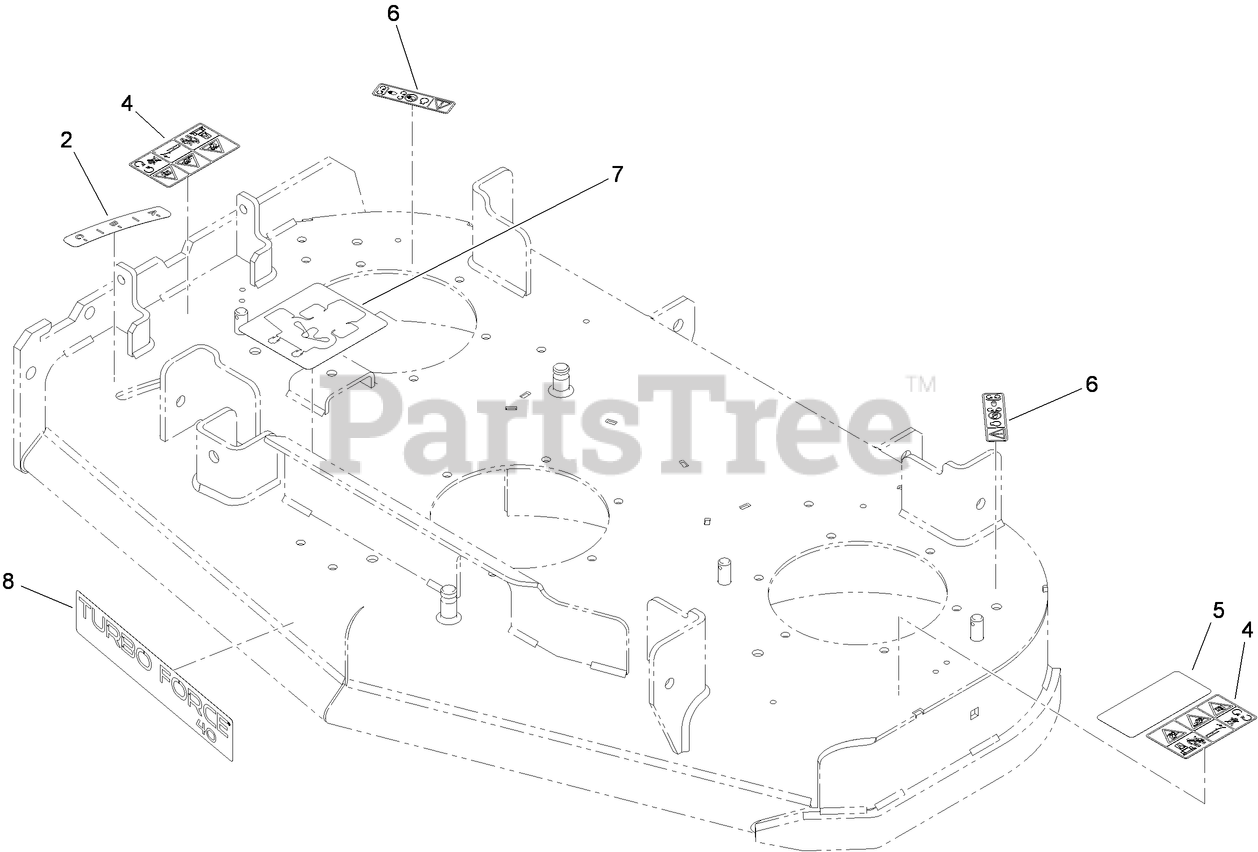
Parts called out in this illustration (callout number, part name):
2	DECAL-SETTING, BAFFLE
4	DECAL-DANGER
5	DECAL-TORQUE, BLADE BOLT
6	DECAL-DANGER
7	DECAL-ROUTING, BELT
